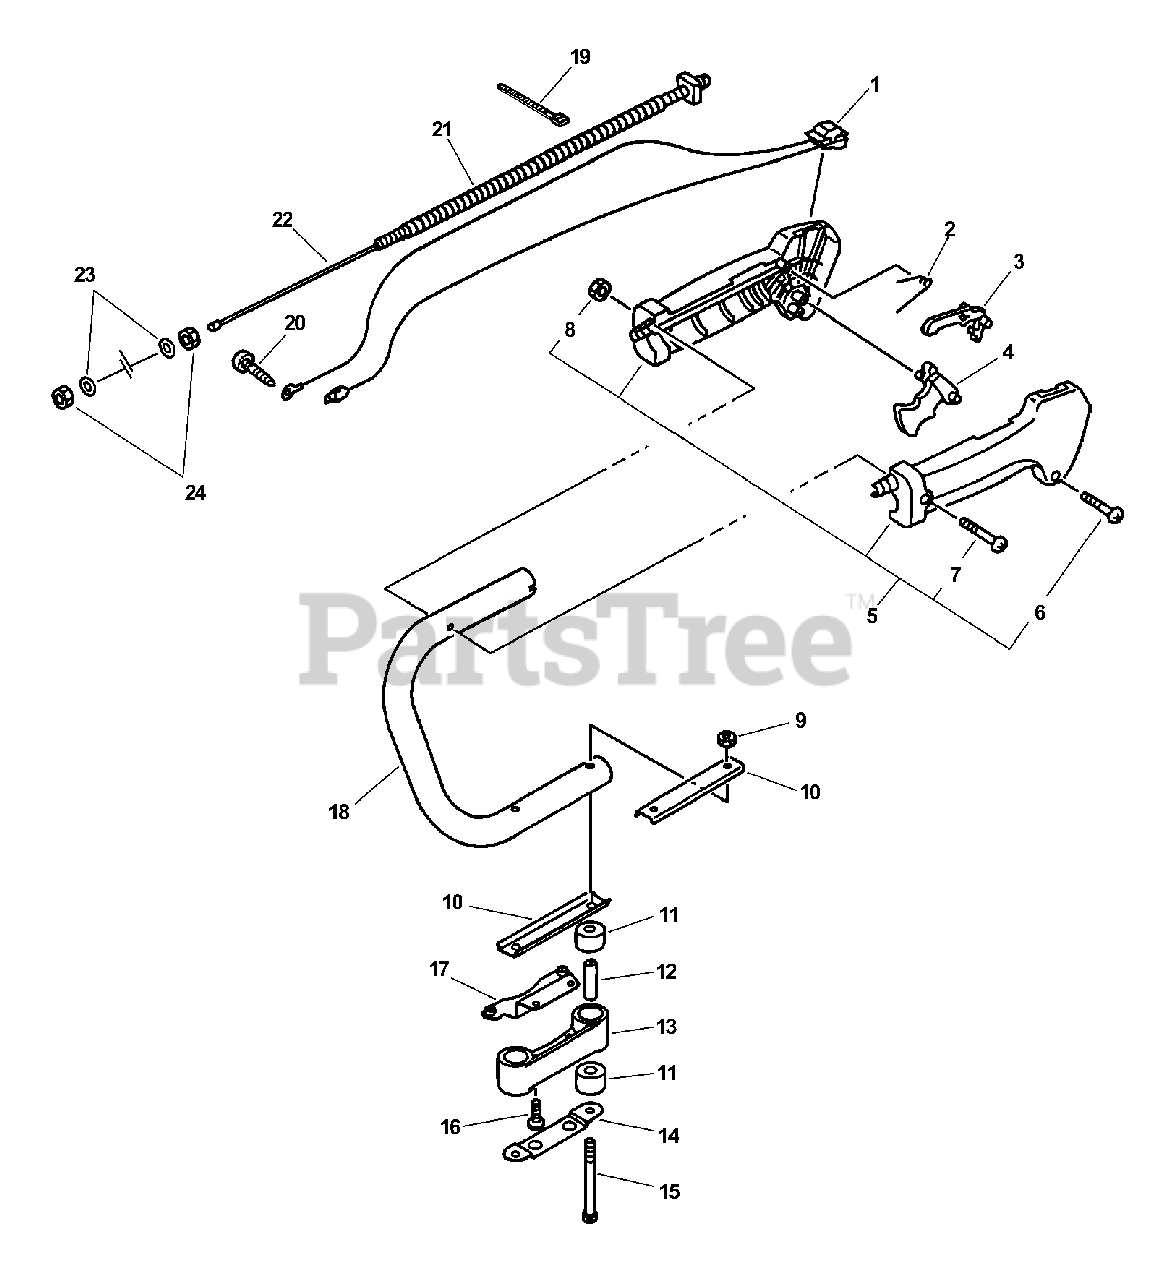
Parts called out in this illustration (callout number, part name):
1	IGNITION SWITCH ASSY
2	SPRING, LOCKOUT LEVER
3	LOCKOUT, THROTTLE
4	TRIGGER, THROTTLE
5	THROTTLE CONTROL ASSY
6	SCREW - 3X25
7	SCREW - 5X30
9	LOCKNUT - 5
10	BRACKET, HANDLE - LOWER
12	SPACER
13	BRACKET, HANDLE
14	PLATE, CUSHION
15	SCREW - 5X60
16	SCREW - 5X16
18	HANDLE - REAR
19	TIE, CABLE
20	SCREW - 5X10
22	CABLE, THROTTLE
23	WASHER - 6
